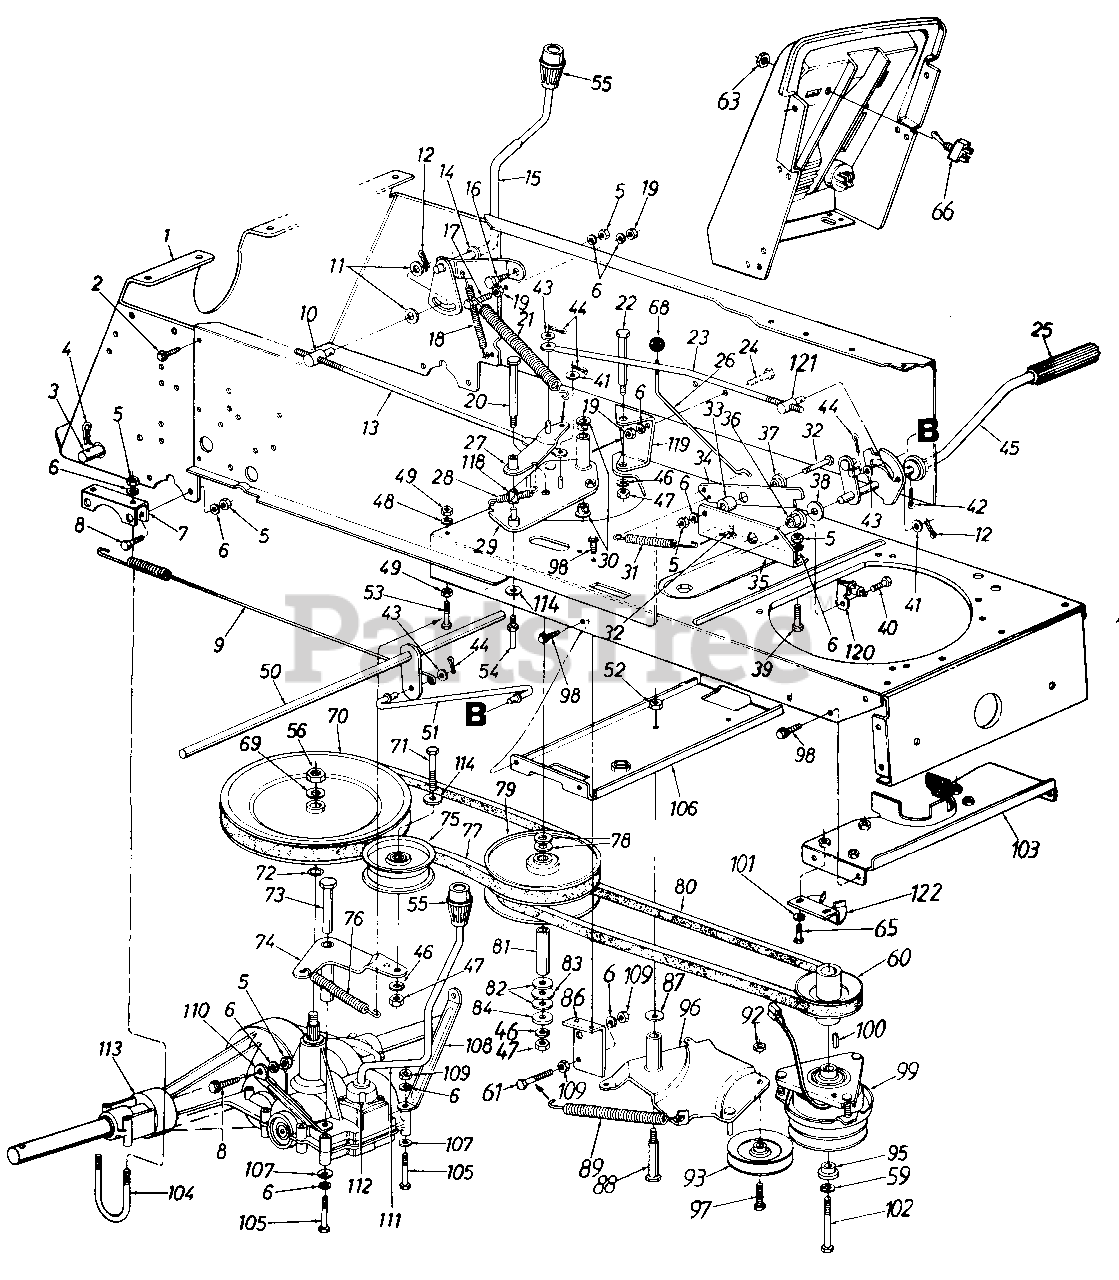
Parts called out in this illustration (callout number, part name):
3	Hitch Rod
4	Hitch Pin Clip
5	Hex Nut 5/16-18 Thd.
6	L-Wash. 5/16" I.D.
7	Transaxle Bracket
8	Hex Bolt 5/16-18 x .75" Lg. (Grade 5)
9	Brake Extension Spring
10	Adjustment Ferrule 3/8-24 Thd.
11	Fl-Wash. .385" I.D. x .87"
12	Internal Cotter Pin
13	Speed Control Link (Rear)
14	Fl-Wash. .531" I.D. x .94"
15	Speed Selector Lever Ass'y.
16	Shld. Bolt .437" Dia. x .162"
17	Hex Bolt 5/16-24 x 1.25" Lg.
18	Extension Spring 3.9" Lg.
19	Hex Nut 5/16-24 Thd. (Grade 5)
20	Hex Bolt 3/8-24 x 4.5" Lg.
21	Extension Spring 11" Lg.
22	Shld. Bolt .625" Dia. x 3.5" Lg.
23	Speed Control Link (Front)
24	Hex Bolt 5/16-24 x .75" Lg.
25	Foot Pad
26	Parking Brake Link
27	Var. Speed Torque Brkt. Ass'y.
28	Extension Spring 2.59" Lg.
29	Pulley Brkt. Sub Ass'y.
30	Flanged Brg. .625" I.D.
31	Extension Spring 2.51" Lg.
32	Hex Bolt 5/16-18 x 1.25" Lg.
33	Spacer .34" I.D. x .88"
36	Hex Flange Brg. .634" I.D.
37	Shld. Spacer .5" Dia.
38	Fl-Wash. .64" I.D. x 1.24"
39	Hex Bolt 5/16-18 x .75" Lg.
40	Hex Tap Scr. #10-32 x 5/8" Lg.
41	Fl-Wash. .406" I.D. x .75" O.D.
42	Cotter Pin 1/8" Dia.
43	Fl-Wash. .34" I.D. x.68" O.D.
44	Cotter Pin 3/32" Dia.
45	Foot Pedal Brkt. Ass'y.
46	L-Wash. 3/8" I.D.
47	Hex Nut 3/8-24 Thd.
48	L-Wash. 1/4" I.D.
49	Hex Nut 1/4-20 Thd.
50	Brake Link Bracket
51	Front Brake Rod Link
52	Hex Cent. L-Nut 3/8-16 Thd.
53	Hex Bolt 1/4-20 x 2.0" Lg.
54	Belt Guard Pin
55	Shift Knob
56	Hex Jam Nut 9/16-18 Thd.
59	L-Wash. 7/16" I.D.
60	Engine Pulley
61	Hex Bolt 5/16-24 x 1.75" Lg.
63	Hex Nut l/2-27 Thd.
65	Hex Bolt 5/16-18 x .75" Lg. (Grade 5)
66	Toggle Switch
68	Ball Knob Brake
69	Bell-Wash. 9/16" I.D. x 1.25"
70	V-Pulley 9-1/4" O.D.
71	Hex Bolt 3/8-24 x 1.75" Lg.
72	Wire Ring
73	Shld. Bolt 5/16-24 Thd.
74	Idler Brkt. Ass'y.
75	Flat Idler 3.5" O.D.
76	Extension Spring 6.12" Lg.
77	V-Belt
78	Teflon Washer 1.20" O.D.
79	Variable Speed Pulley 6" Dia.
80	V-Belt
81	Pivot Bushing
82	Fl-Wash. .56" I.D. x 1.0" O.D.
83	Thrust Brg. .56" I.D. x 1.25"
84	Retainer Cup
86	Parking Brake Mtg. Brkt.
87	Bell-Wash. .38" I.D. x .88" O.D.
88	Shld. Bolt .498" Dia. x 2.05"
89	Extension Spring 4.0" Lg.
92	Hex Cent. L-Nut 3/8-24 Thd.
93	V-Belt Idler
95	Shoulder Spacer
96	Idler Brkt. Deck Ass'y.
97	Hex Bolt 3/8-24 x 1.5" Lg.
98	Hex TT-Tap Scr. 1/4-20 x .5"
99	Electric Clutch
100	Sq. Key 1/4 x 1.5" Lg.
101	Bell-Wash. .345" I.D. x .88"
102	Hex Bolt 7/16-20 x 3.75" Lg.
103	Belt Keeper Brkt. Ass'y.
104	U-Bolt
105	Hex Bolt 5/16-24 x 2.25" Lg.
106	Deck Idler Support Brkt.
107	Fl-Wash. .344" I.D. x .62" O.D.
108	Front Trans. Support Brkt. L.H.
109	Hex Nut 5/16-24 Thd.
110	Front Trans. Support Brkt. R.H.
111	Shift Lever Ass'y. Complete
112	Socket Hd. Cap Scr. #10 x 24
113	2-5peed Transmission Comp.
114	Fl-Wash. 3/8" I.D. x 1.0" O.D.
118	Nyliner Flanged Brg.
119	Variable Speed Support Brkt.
120	Safety Switch (Clutch)
121	Adjustment Ferrule 3/8-24 Thd.
